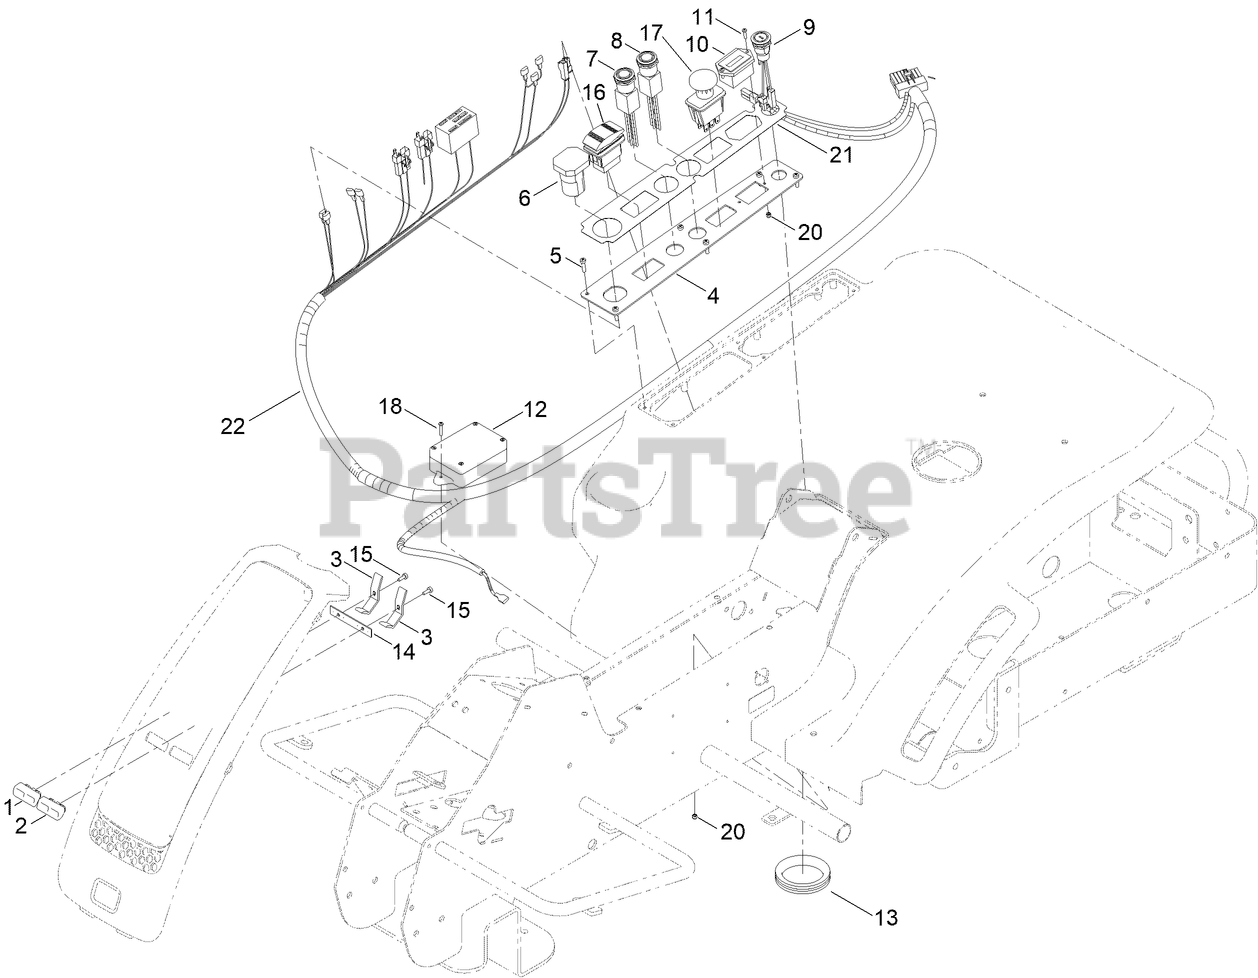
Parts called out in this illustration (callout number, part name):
1	CASING, LIGHT (RIGHT, FRONT)
2	CASING, LIGHT (LEFT, FRONT)
3	BRACKET, LED LIGHTS
4	PLATE, SWITCHES
6	USB SWITCH
7	RMO, BUTTON
8	CCT, BUTTON
9	SWITCH, IGNITION
10	INDICATOR, BATTERY LEVEL
12	CONTROL BOX, ASM
13	INSERT, RUBBER CABLE SMALL
14	PLATE, LIGHTS
16	DIRECTION SWITCH ASM
17	CUTTER BUTTON ASM
20	NUT-NYLOC
21	DECAL - CONTROL PANEL
22	WIRING HARNESS, CONTROL PANEL
